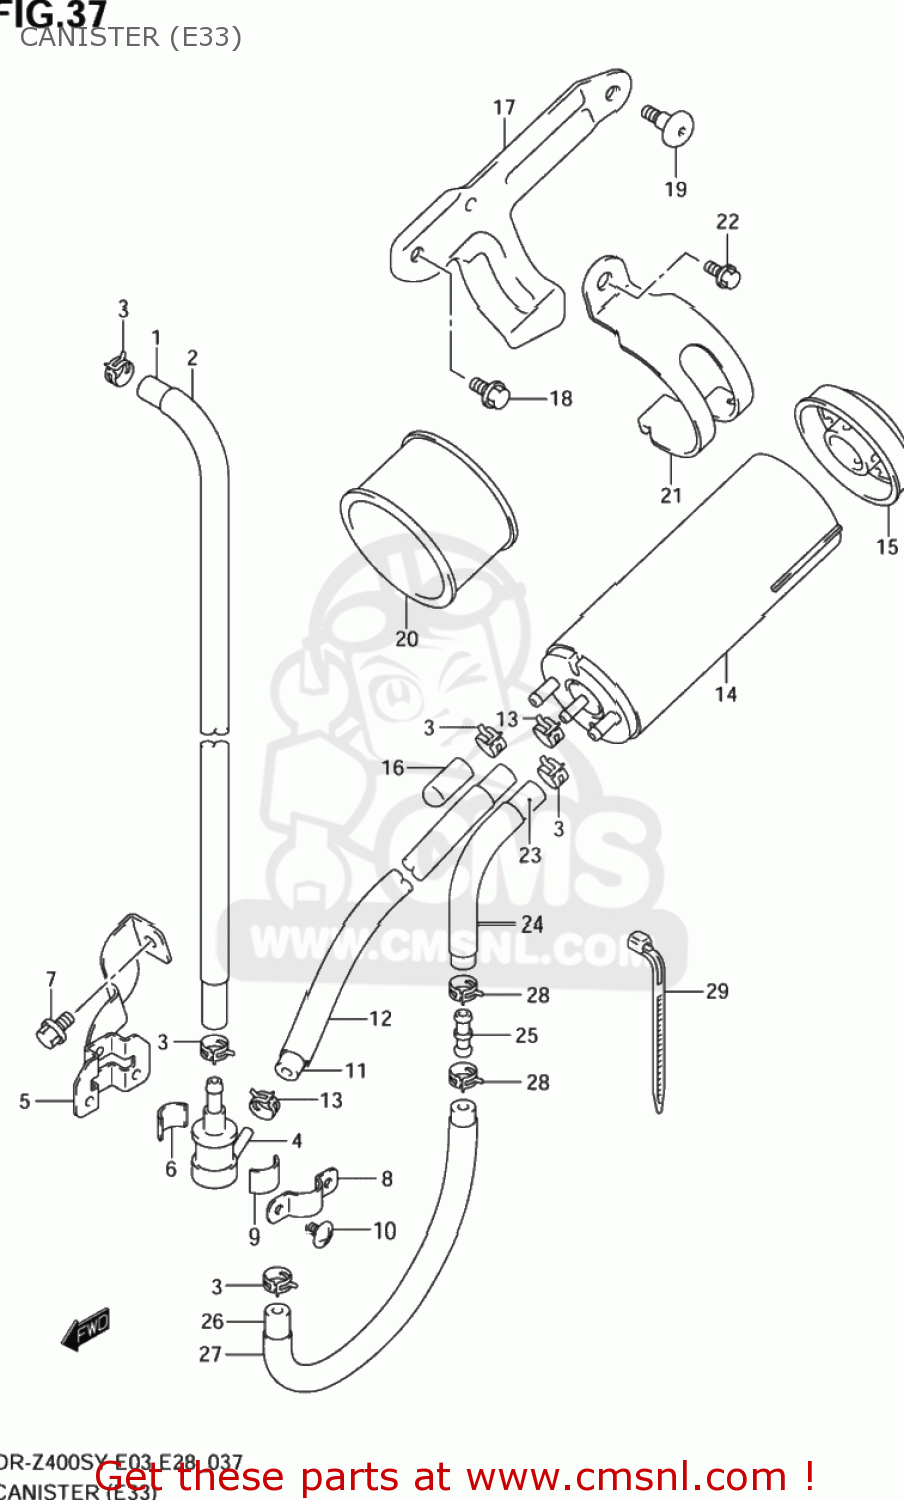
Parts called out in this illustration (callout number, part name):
1	HOSE,TANK & BREATHER VALVE
2	PROTECTOR(14.5X15.5X600)
3	CLIP
4	VALVE,FUEL TANK BREATHER
5	BRACKET,BREATHER VALVE
6	CUSHION
7	BOLT
8	PLATE,FUEL TANK BREATHER NO.2
9	CUSHION
10	SCREW
11	HOSE,BREATHER VALVE & CANISTER
12	HOSE
13	CLIP
14	CANISTER ASSY,CHARCOAL
15	CAP,CANISTER
16	CAP,OD:11.5
17	BRACKET,CANISTER
18	BOLT
19	BOLT(6X16)
20	CUSHION,CANISTER
21	HOLDER,CANISTER
22	BOLT
23	HOSE,CSTR & CARB PURGE
24	PROTECTOR(14.5X15.5X600)
25	UNION
26	HOSE,CANISTER & CARB PURGE NO2
27	PROTECTOR(14.5X15.5X600)
28	CLIP
29	CLAMP(L:145)
